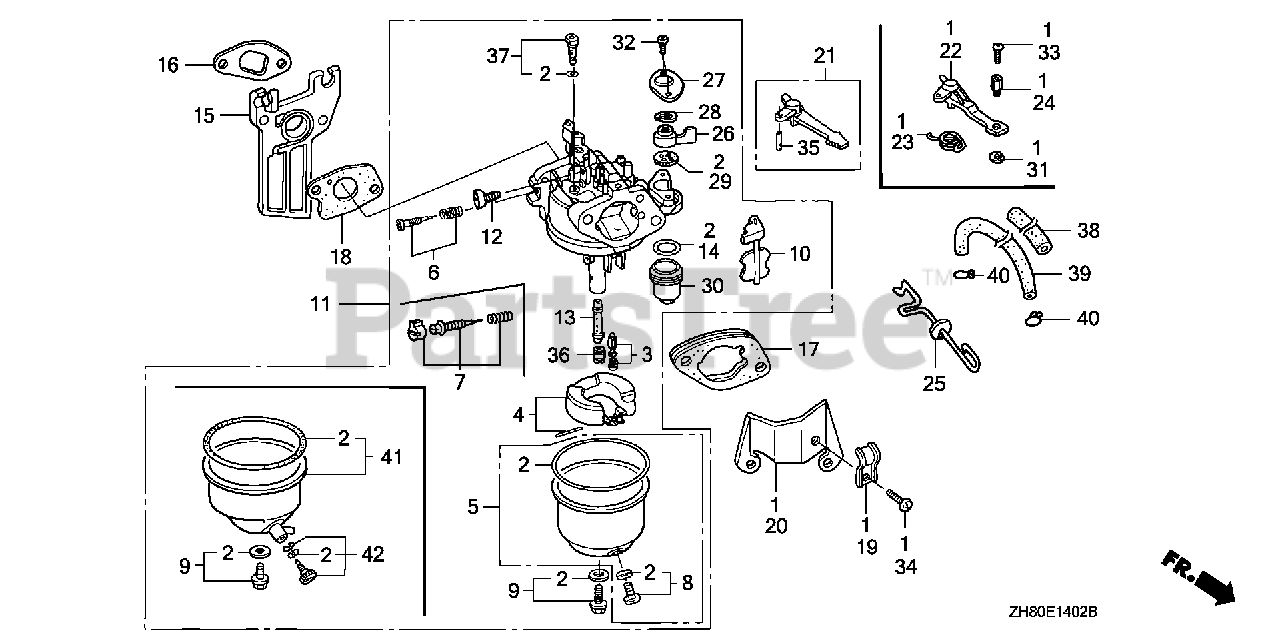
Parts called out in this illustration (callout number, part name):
2	GASKET SET (CARBURETOR NO.)
3	VALVE SET, FLOAT (SEAT NOT INCLUDED)
5	CHAMBER SET, FLOAT (CARBURETOR NO.)
6	SCREW SET, PILOT (CARBURETOR NO.)
8	SCREW SET, DRAIN (CARBURETOR NO.)
9	SCREW SET
10	CHOKE SET (CARBURETOR NO.)
11	CARBURETOR ASSY. (BE65B B/C)
11	CARBURETOR ASSY. (BE06J C)
12	SCREW, THROTTLE STOP
13	NOZZLE, MAIN (CARBURETOR NO.)
14	GASKET, FUEL STRAINER CUP
15	INSULATOR, CARBURETOR
16	GASKET, INSULATOR
17	SPACER, CARBURETOR
18	GASKET, CARBURETOR
21	LEVER, CHOKE (STD)
26	LEVER, PETCOCK (CARBURETOR NO.)
27	PLATE, LEVER SETTING (CARBURETOR NO.)
28	SPRING, PETCOCK LEVER
29	GASKET, PETCOCK
30	CUP, FUEL STRAINER
32	SCREW, PAN (3X6)
32	SCREW, PAN (3X8) (CARBURETOR NO.)
35	PIN, SPRING (2X12)
36	JET, MAIN (#72) (CARBURETOR NO.)
36	JET, MAIN (#65) (CARBURETOR NO.)
36	JET, MAIN (#68) (CARBURETOR NO.)
36	JET, MAIN (#70) (CARBURETOR NO.)
36	JET, MAIN (#65)
36	JET, MAIN (#70)
37	JET SET, PILOT (#35) (CARBURETOR NO.)
37	JET SET, PILOT (#38) (CARBURETOR NO.)
